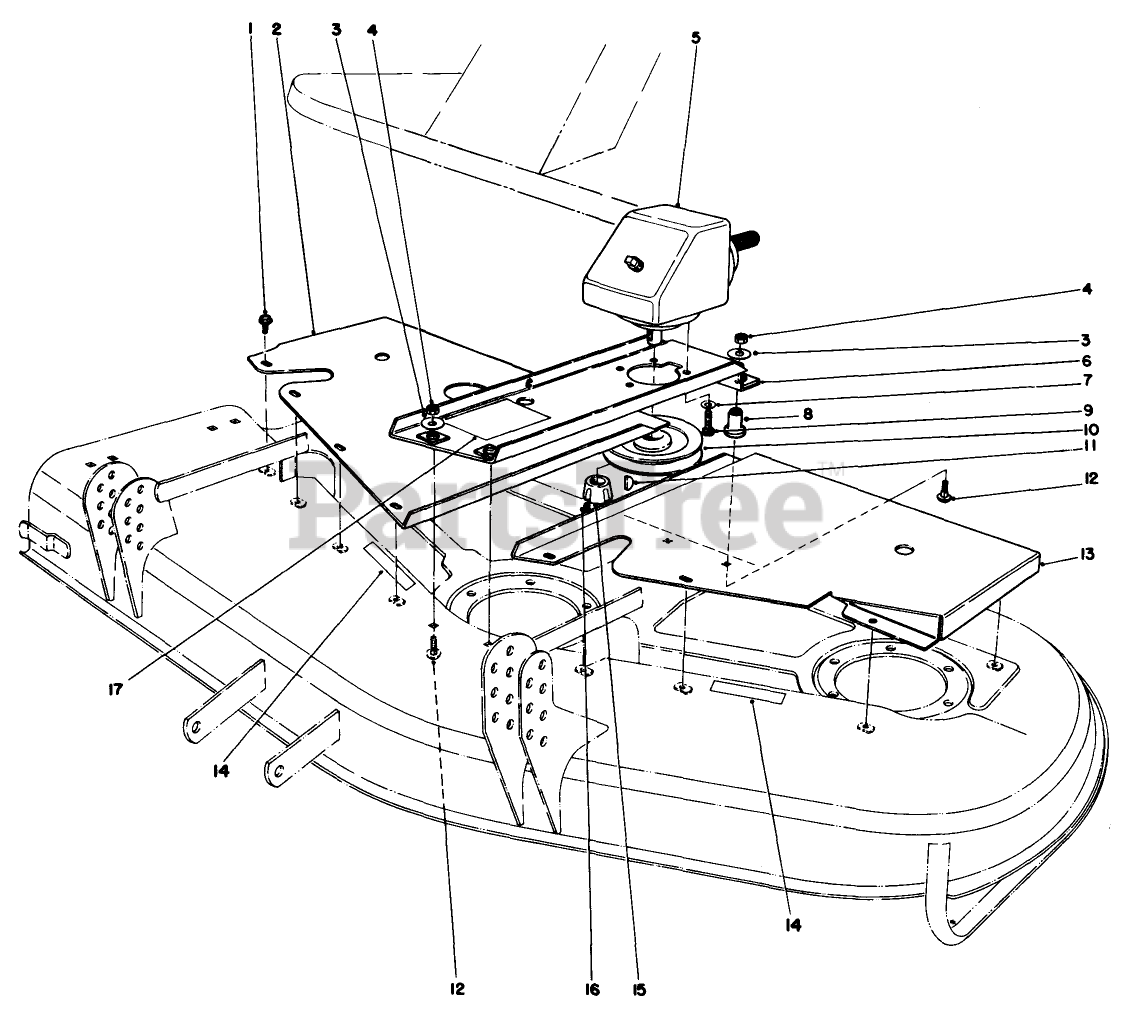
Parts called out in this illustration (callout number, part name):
1	SCREW-HHFTF
2	RH COVER WA R
3	WASHER
4	NUT-LOCK, SIDE
5	GEAR BOX ASM
6	GEARBOX BASE WA R
7	WASHER-LOCK
8	MOUNT
9	SCREW-HSH
10	PULLEY
11	KEY-WOODRUFF
12	SCREW-CARR
13	LH COVER WA R
14	DECAL-DANGER
15	Bushing-Taper Lock (Incl. Ref. #16)
16	SCREW-SET, HSH
17	DECAL
